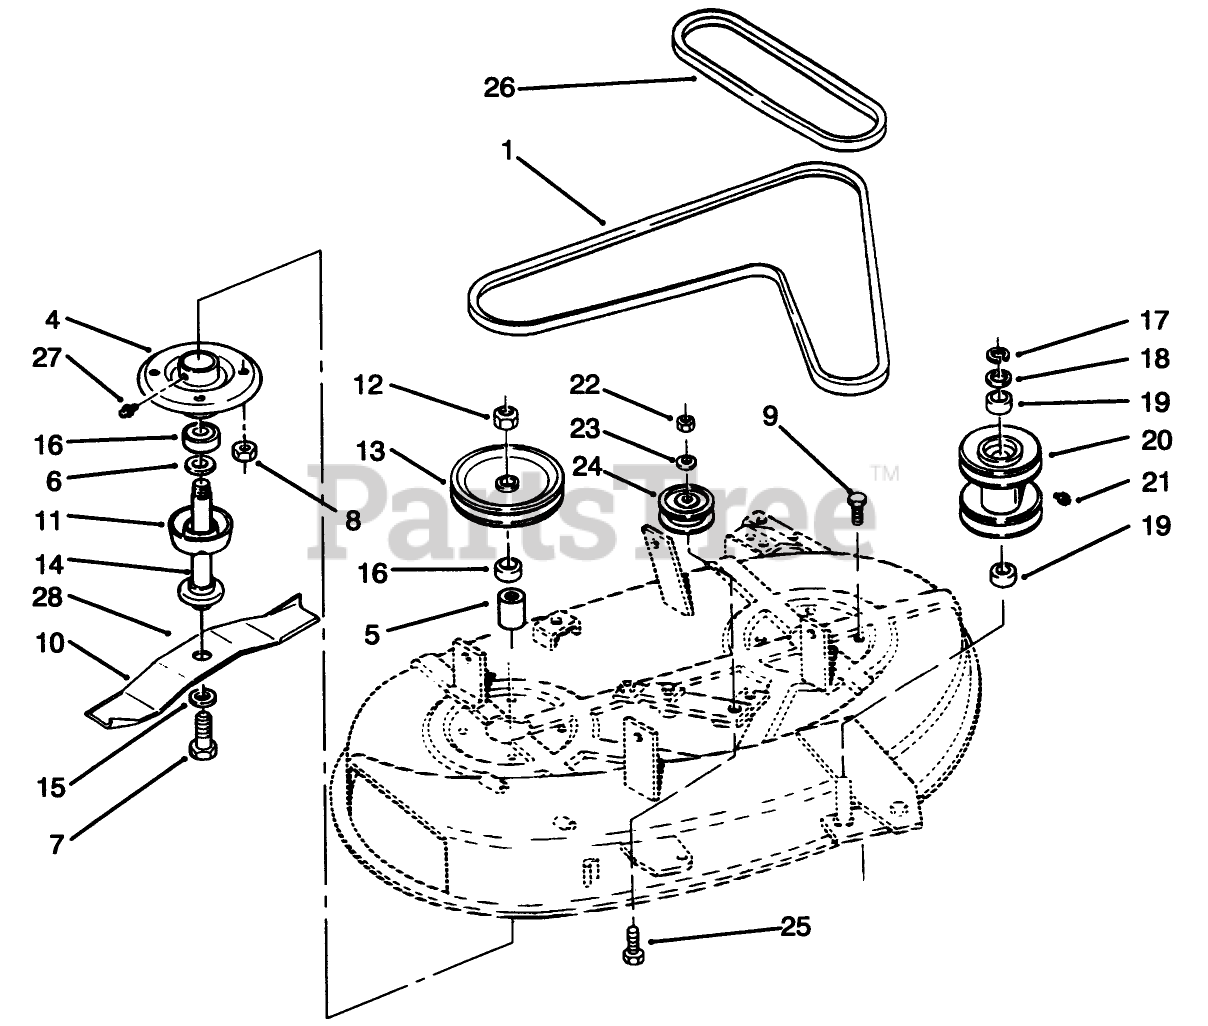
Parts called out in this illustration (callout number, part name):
1	V-BELT
4	Housing-Spindle
5	SPACER
6	SPACER-HARDNED
7	SCREW-HH
8	NUT-LOCK, NI
9	SCREW-HH
10	Blade
11	SHIELD-BEARING
12	NUT-HEX
13	PULLEY
14	SHAFT-SPINDLE
15	WASHER
16	BEARING-BALL
17	RETAINING RING
18	O RING
19	BEARING-BALL
20	PULLEY-COUNTER SHAFT
21	FITTING-GREASE
22	NUT-LOCK, NI
23	WASHER-FLAT
24	Pulley
25	SCREW-HH
26	V-BELT
27	ZERK FITTING
